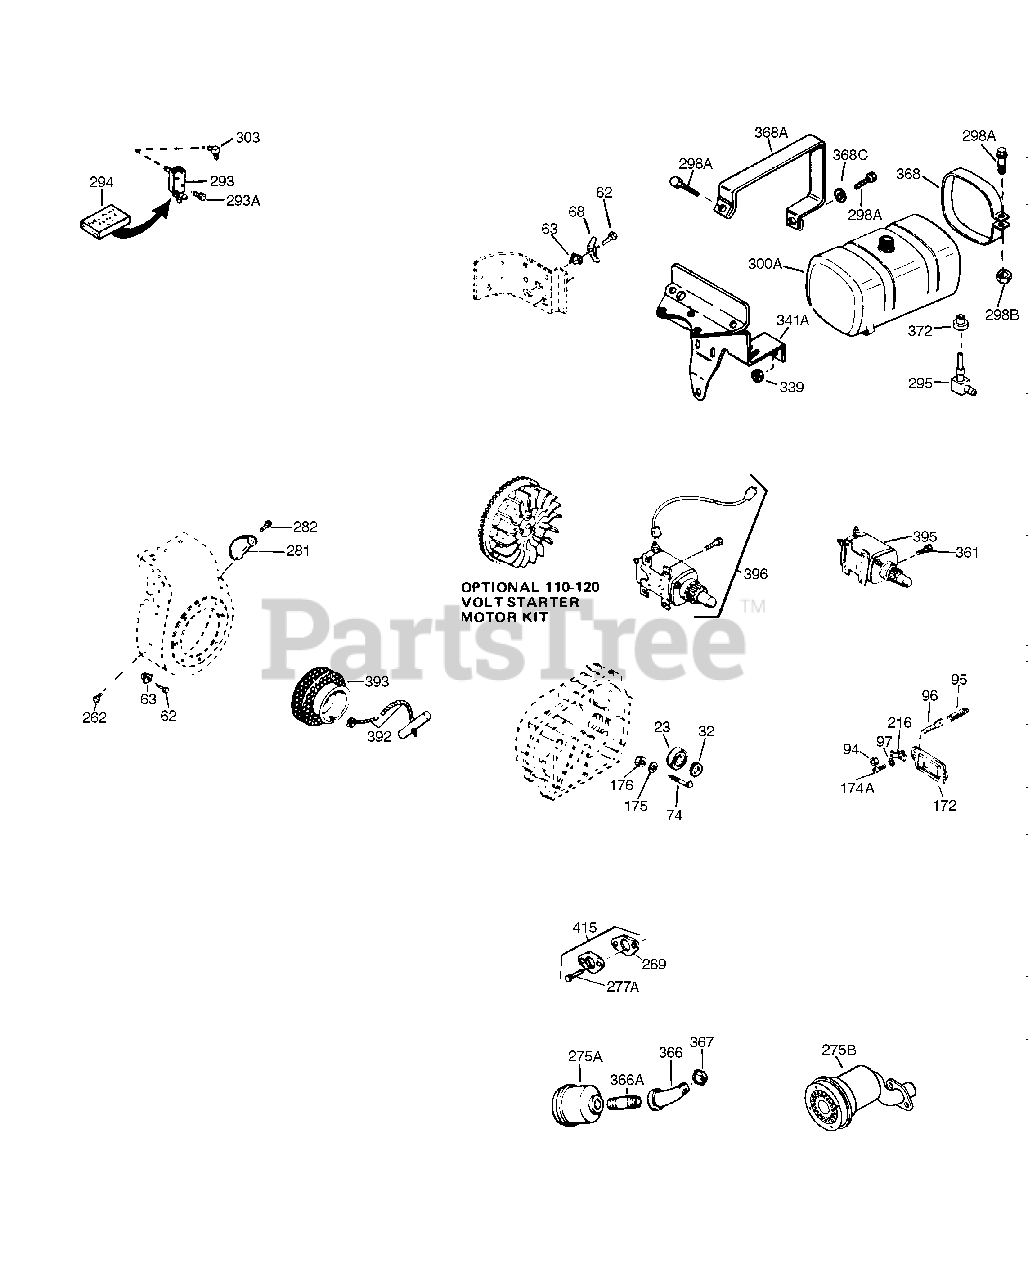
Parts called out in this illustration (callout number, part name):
129	Screw, 5/16-18 x 2-1/2"
131	Screw, 5/16-18 x 2-1/2"
172	Valve Cover
262	Screw, T-40, 5/16-24 x 21/32"
269	* Exhaust Manifold Gasket
277A	Screw, 5/16-18 x 3/4"
295	Fuel Shut-Off Valve (Incl. 292) also available in Packaged Part #740073
